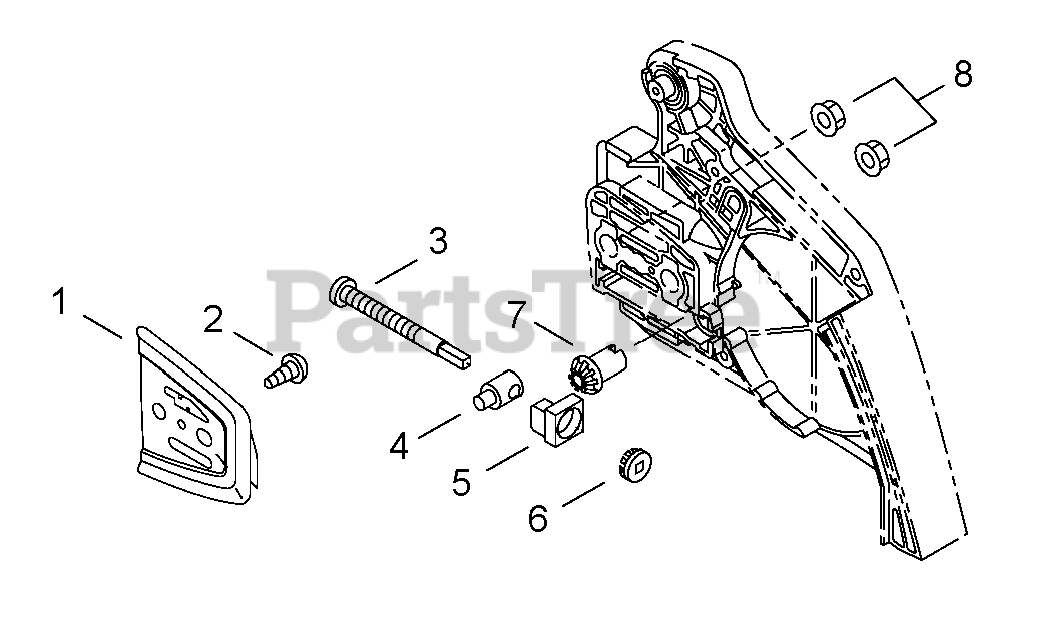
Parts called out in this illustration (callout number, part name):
1	PLATE, GUIDE - INNER
2	SCREW 4×12
3	SCREW, CHAIN TENSION
4	TENSIONER, CHAIN
5	COLLAR 8
6	GEAR, BEVEL
7	GEAR, BEVEL
8	NUT, FLANGE M8×1.25
